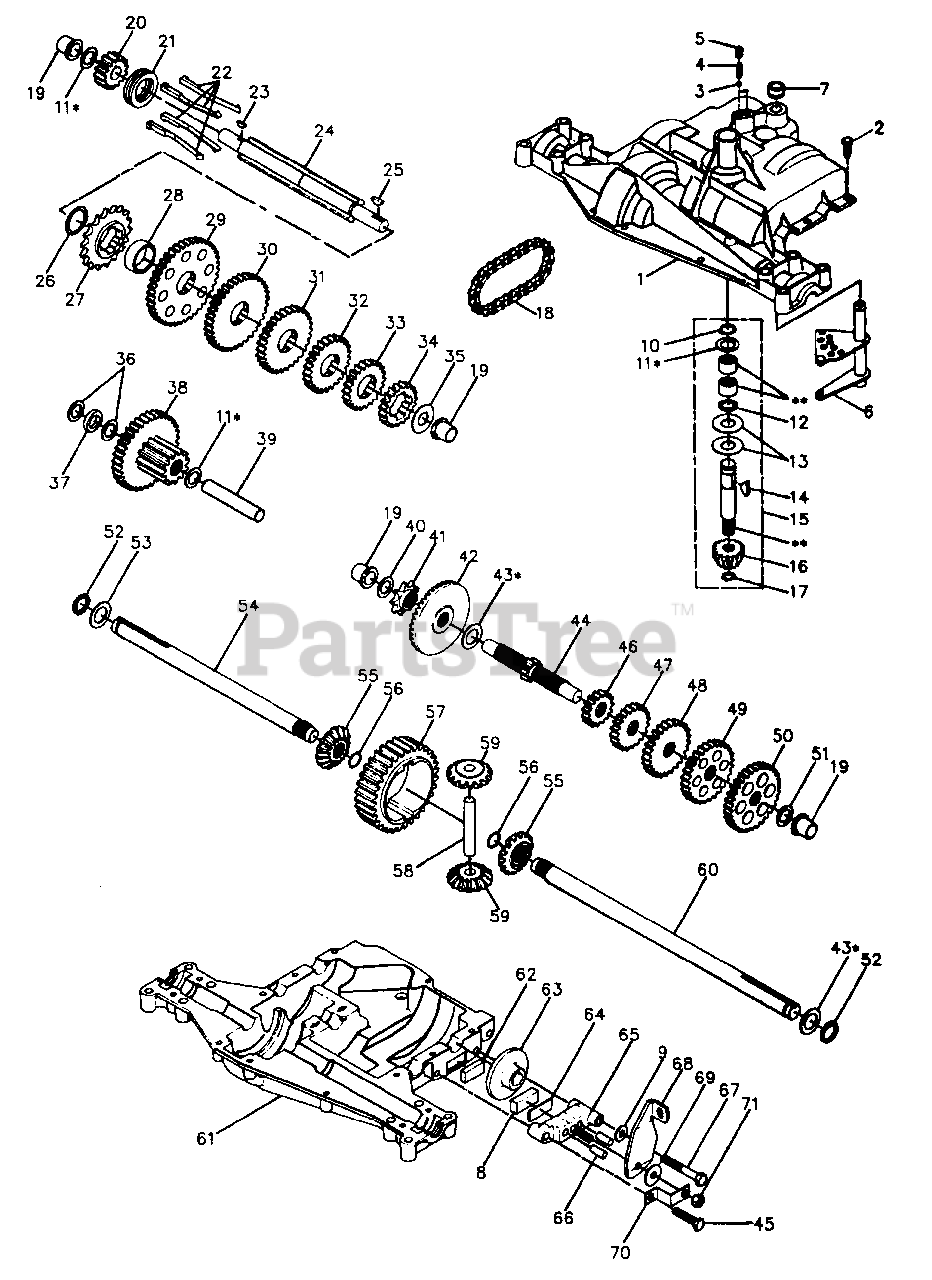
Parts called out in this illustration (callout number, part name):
1	Housing, Upper (AYP part number)
2	Screw, Tapping 1/4 - 20 x .734 Lg.
3	Ball, Detent
4	Spring, Detent
5	Screw, Set
6	Assembly, Shifter (AYP part number)
7	V-Ring
8	Puck, Friction
9	Washer, Plain .325 x .750 x .059
10	Ring, Retaining
11	Washer, Plain .632 x 1.00 x .010
11	Washer, Plain .632 x 1.00 x .020
11	Washer, Plain .632 x 1.00 x .026
11	Washer, Plain .632 x 1.00 x .031
11	Washer, Plain .632 x 1.00 x .036
11	Washer, Plain .632 x 1.00 x .041
11	Washer, Plain .632 x 1.00 x .046
11	Washer, Plain .632 x 1.00 x .050
11	Washer, Plain .632 x 1.00 x .060
11	Washer, Plain .632 x 1.00 x .082
12	O-Ring
13	Washer, Plain .632 x 1.38 x .046
14	Key, Woodruff # 9
15	Assembly, Kit, Input Shaft
16	Pinion, Bevel, 14 T
17	Ring, Retaining
18	Chain, 24 Pitches
19	Bearing, Flange
20	Gear, Spur, 14T
21	Collar, Clutch (AYP part number)
22	Key, Clutch
23	Key, Woodruff # 3 (AYP part number)
24	Shaft, Intermediate
25	Key, Woodruff # 61
26	Ring, Retaining
27	Sprocket, 18 T
28	Spacer
29	Gear, Spur 40 T
30	Gear, Spur 35 T (AYP part number)
31	Gear, Spur 30 T
32	Gear, Spur 25 T
33	Gear, Spur 22 T
34	Gear, Spur 19 T (AYP part number)
35	Washer, Plain .640 x 1.37 x .061
36	Washer, Plain .632 x 1.00 x .026
37	Spacer .630 x 1.00 x .169
38	Assy., Gear, Comb. 12 T & 35 T
39	Shaft, Idler (AYP part number)
40	Washer, Plain .631 x 1.00 x .015
41	Sprocket, 9 T
42	Gear, Bevel, 42 T
43	Washer, Plain .758 x 1.12 x .010
43	Washer, Plain .758 x 1.12 x .015
43	Washer, Plain .758 x 1.12 x .020
43	Washer, Plain .758 x 1.12 x .025
43	Washer, Plain .758 x 1.25 x .020
43	Washer, Plain .758 x 1.25 x .025
43	Washer, Plain .758 x 1.25 x .031
43	Washer, Plain .758 x 1.25 x .035
43	Washer, Plain .758 x 1.25 x .040
43	Washer, Plain .758 x 1.25 x .045
43	Washer, Plain .758 x 1.25 x .050
44	Shaft, Drive
45	Screw, Tapping 5/16 x 18 x 1.44 Large
46	Gear, Spur, 15 T (AYP part number)
47	Gear, Spur, 20 T
48	Gear, Spur, 25 T
49	Gear, Spur, 28 T
50	Gear, Spur, 31 T
51	Washer, Plain .632 x 1.00 x .060
52	Seal, Felt (AYP part number)
53	Washer, Plain .758 x 1.25 x .062
54	Axle, L.H. (AYP part number)
55	Gear, Miter, 15 T
56	Ring, Retaining
57	Gear, Spur, 32 T (AYP part number)
58	Shaft, Cross
59	Gear, Miter, 15 T
60	Axle, R.H. (AYP part number)
61	Housing, Lower
62	Puck, Friction
63	Disc, Brake
64	Spacer
65	Jaw, Brake
66	Pin, Dowel
67	Screw, Tapping 5/16 - 18 x 2.25 (AYP part number)
68	Lever, Actuating
69	Washer, Plain .321 x 1.00 x .055
70	Bracket, Anti-Rotation
71	Locknut 5/16 - 24
72	Grease (AYP part number)
